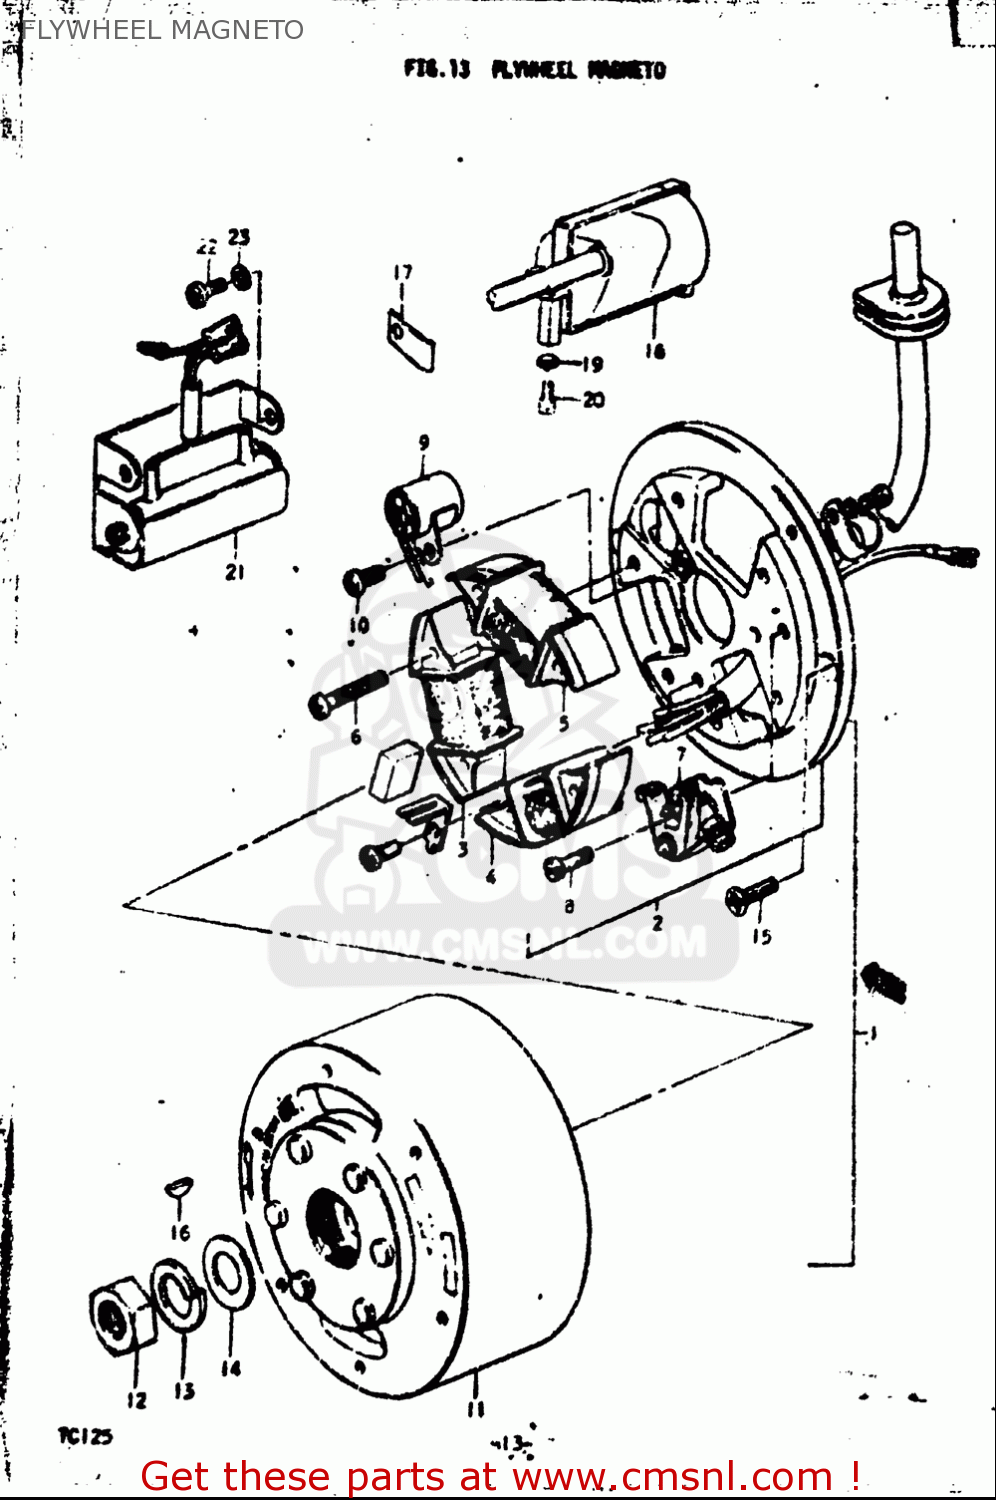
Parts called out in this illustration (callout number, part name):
5	COIL,PRIMARY
6	SCREW(4X30)
7	POINT ASSY,CONTACT
8	.SCREW
9	CONDENSER
10	SCREW
12	NUT
13	WASHER,LOCK
14	WASHER
15	SCREW
16	KEY
17	CLAMP(L:65)
18	COIL ASSY,IGNITION
19	WASHER,LOCK
20	BOLT
22	SCREW(5X6)
23	WASHER,LOCK
